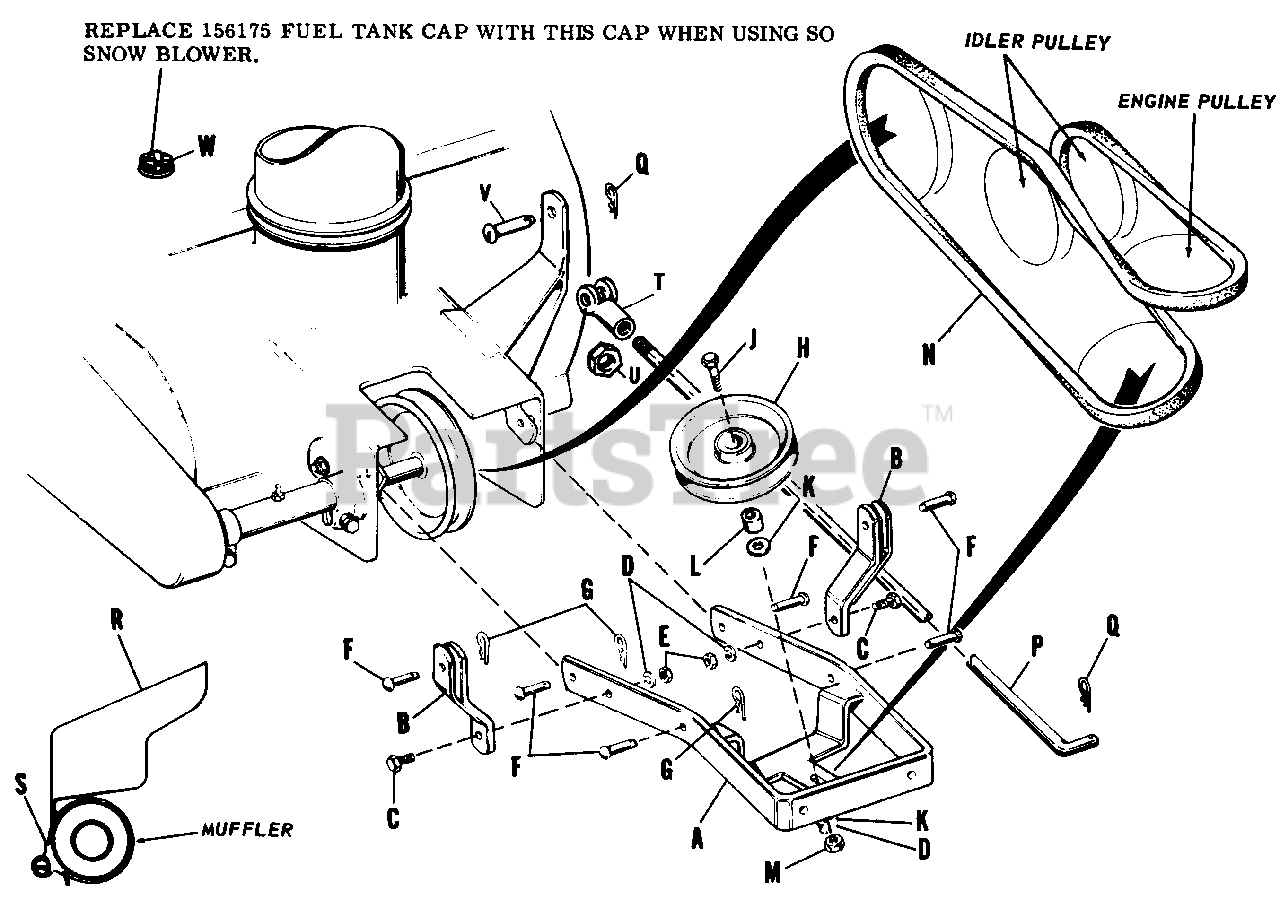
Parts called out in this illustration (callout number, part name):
A	Push Arm Assembly
B	Support Arm Assembly
C	Hex Capscrew, 3/8"-16 x 1-1/4" lg.
D	Lock Washer, 3/8 "
E	Hex Nut, Full, 3/8"-16
G	Spring Clip
J	Hex Capscrew, 3/8"-16 x 1-3/4" lg.
K	Plain Washer, 3/8"
M	Hex Nut, Full, 3/8"-16
P	Front Lift Rod
Q	Spring Clip
R	Deflector
U	Hex Nut,Full, 1/2-20
W	Cap (winter) Fuel Tank
